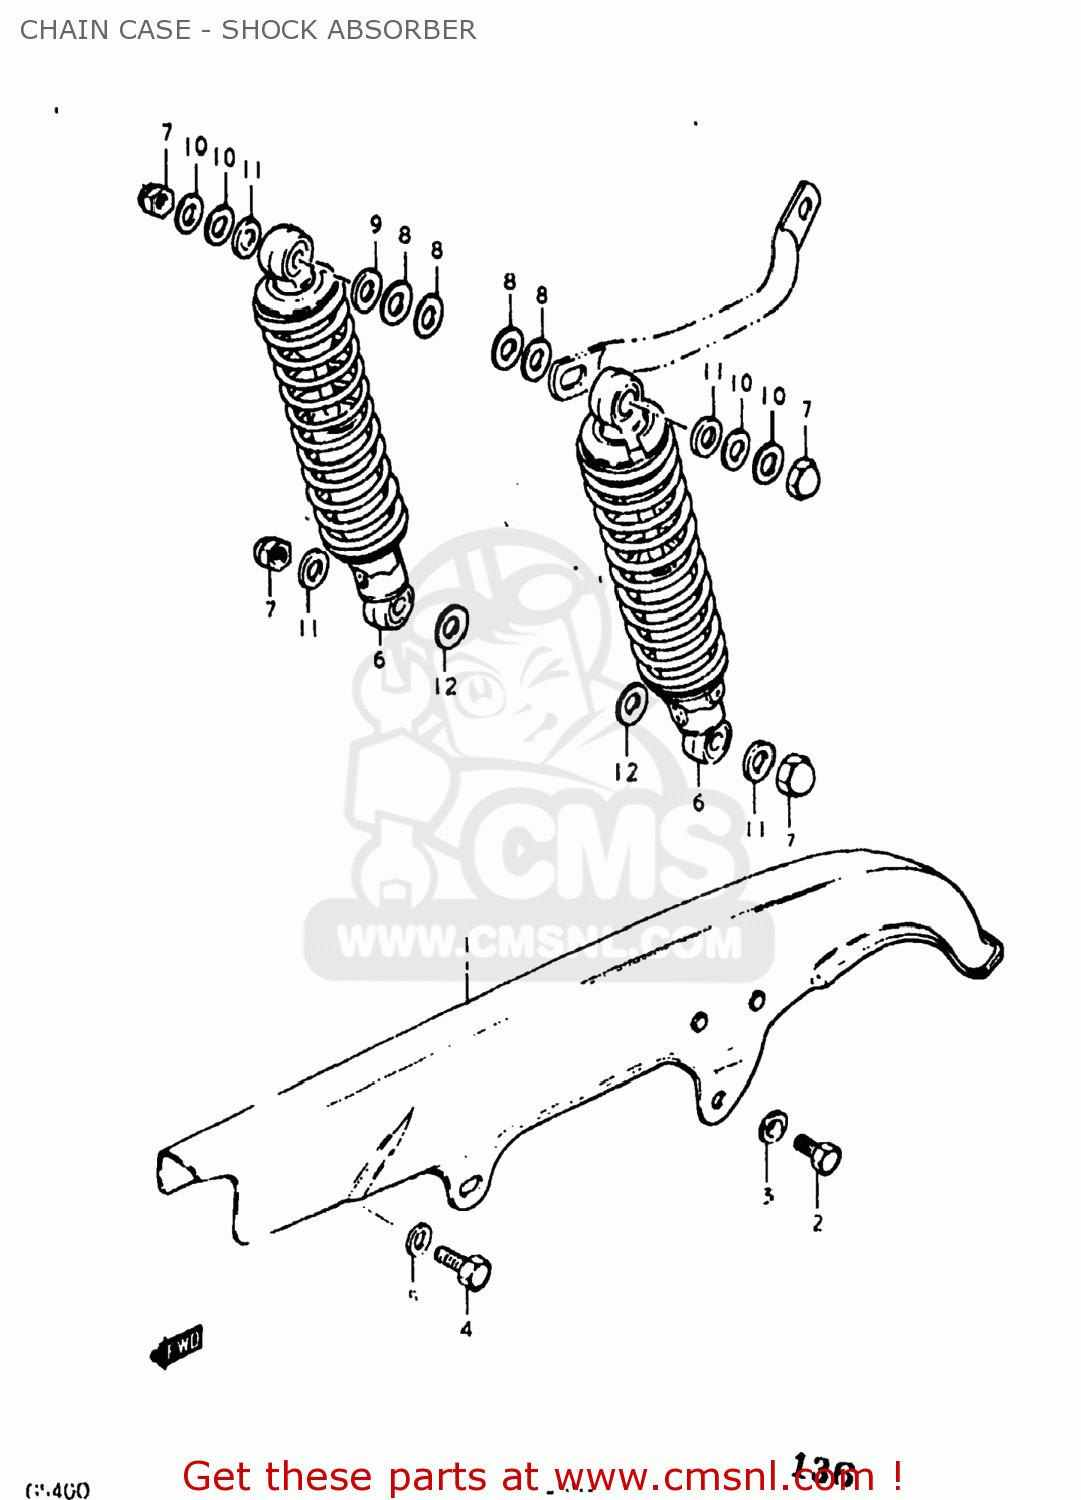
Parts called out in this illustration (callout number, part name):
1	CASE,CHAIN
2	BOLT(6X8)
3	WASHER
4	BOLT
5	WASHER(6.5X18X1)
6	ABSORBER ASSEMBLY,REAR SHOCK
7	NUT
8	WASHER
9	WASHER (12.5X24X3.2)
10	WASHER
11	WASHER(10.5X24X3.2)
12	WASHER (12.5X24X1.6)
